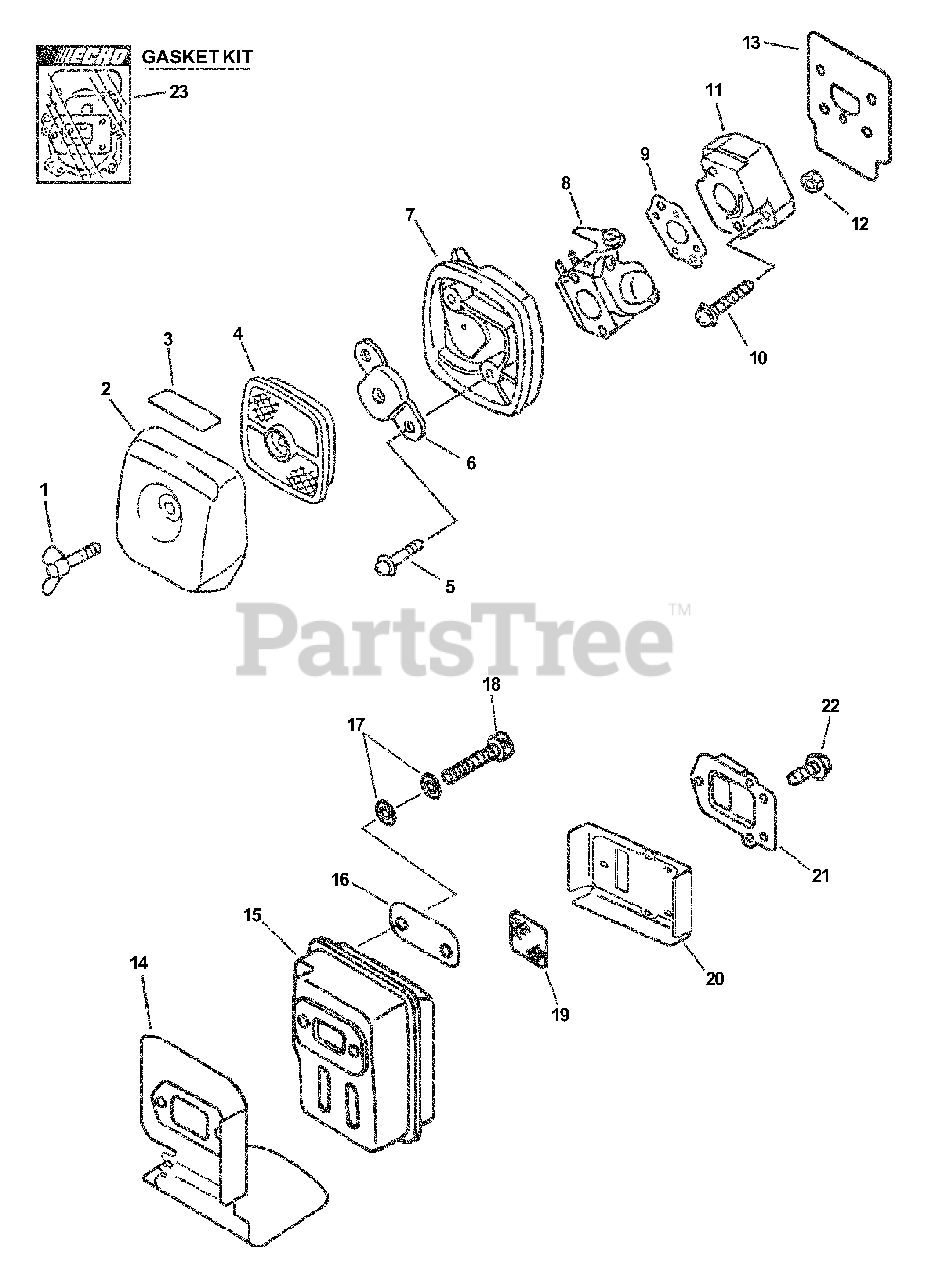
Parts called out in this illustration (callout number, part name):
1	BOLT, WING 5×20
2	COVER, AIR FILTER - GRAY
3	LABEL, CHOKE
4	FILTER, AIR - SINGLE LAYER
5	SCREW 5×65
6	PLATE, PREVENT
7	CASE, AIR FILTER - GRAY
8	CARBURETOR - C1U-K58
9	GASKET, INTAKE
10	SCREW 5×20
11	INSULATOR, INTAKE
12	NUT M5
13	HEAT SHIELD, INTAKE
14	SHIELD, EXHAUST
15	MUFFLER
16	PLATE, EYE
17	CONICAL WASHER
18	BOLT 5×55
19	SCREEN, SPARK ARRESTER
20	GASKET, EXHAUST
21	GUIDE, EXHAUST
22	SCREW 4×10
23	GASKET KIT
